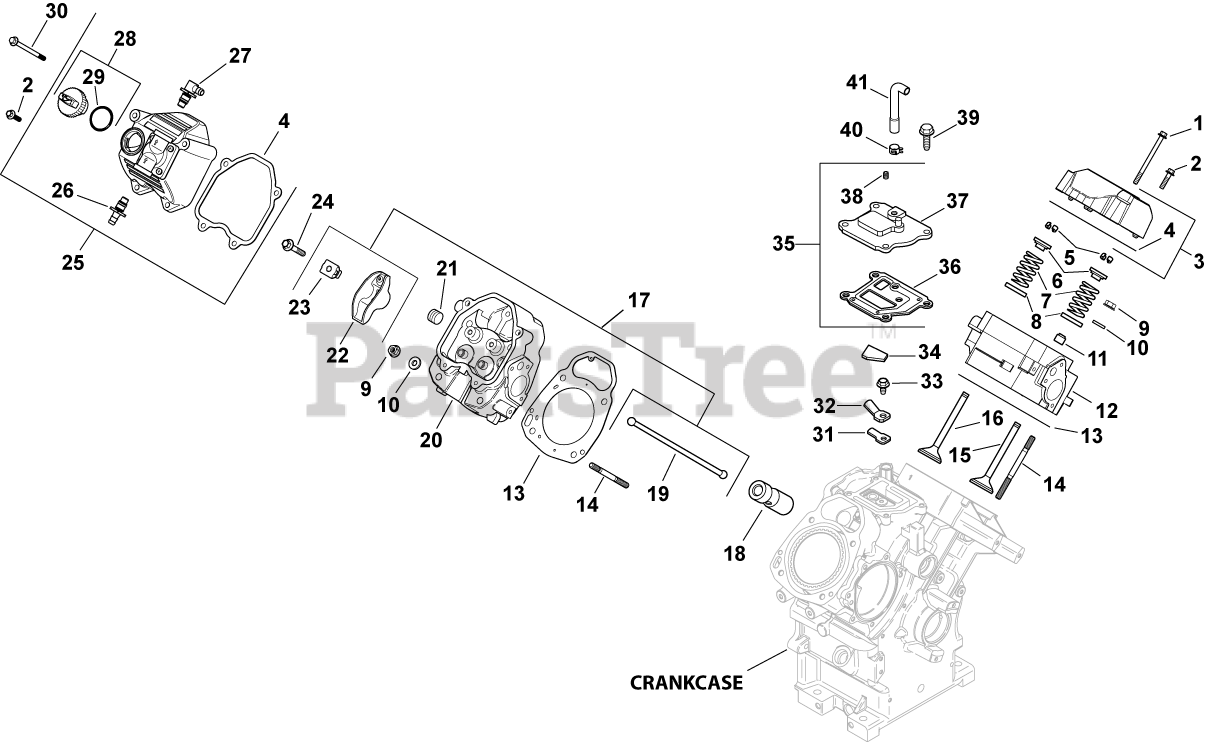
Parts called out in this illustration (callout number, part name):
1	SCREW, FLG M6X1.0X55
2	SCREW - USE 25 086 124-S
3	KIT, ROCKER COVER
4	GASKET, VALVE COVER
5	KIT, RETAINER
6	RETAINER, VALVE SPRING - USE 25 173 28-S
7	SPRING, VALVE
8	RETAINER-USE 235011-S
9	NUT, FLG M8X1.25
10	WASHER, FLAT 5/16"
11	SEAL, VALVE STEM - (#2503214S)
12	KIT,CYLINDER HEAD #1
13	KIT, CYLINDER HEAD GASKET
15	VALVE, INTAKE (STD)
16	VALVE, EXHAUST (STD) - USE 32 016 01-S
17	KIT, VALVE TRAIN
18	LIFTER, HYDRAULIC VALVE-USE 25 351 10-S
19	ROD, PUSH
20	KIT,CYLINDER HEAD #2
21	PLUG, PIPE
22	ARM, ROCKER
23	PIVOT, ROCKER ARM
24	SCREW, ROCKER ARM PIVOT-USE M-640034-S
25	KIT, FUEL PUMP/ROCKER COVER
26	KIT, STRAIGHT FITTING
27	KIT, 90 DEG. FITTING
28	CAP ASSY, OIL FILL (YELLOW)
29	O-RING-USE 24 153 32-S
30	SCREW, FLG M6X1.0X80
31	REED, BREATHER
32	RETAINER, REED
33	SCREW, FLG THD FRM M5X.8X10
34	FILTER, BREATHER-USE 24 050 11-S
35	KIT, BREATHER ASSEMBLY
36	GASKET, BREATHER-USE 24 041 67-S
37	COVER, BREATHER -USE 24 033 01-S
38	PLUG, CTSK PIPE 1/8"
39	SCREW,FLG THD FRM M6X1.0X20-(#25086396S)
40	CLAMP, BAND SPRING HOSE-(#2523737S)
41	HOSE, BREATHER -USE 24 326 91-S
2401602-S	VALVE, EXHAUST (.25)
2401702-S	VALVE, INTAKE (.25)
6603205-S	SEAL, VALVE STEM - (#2503214S)
